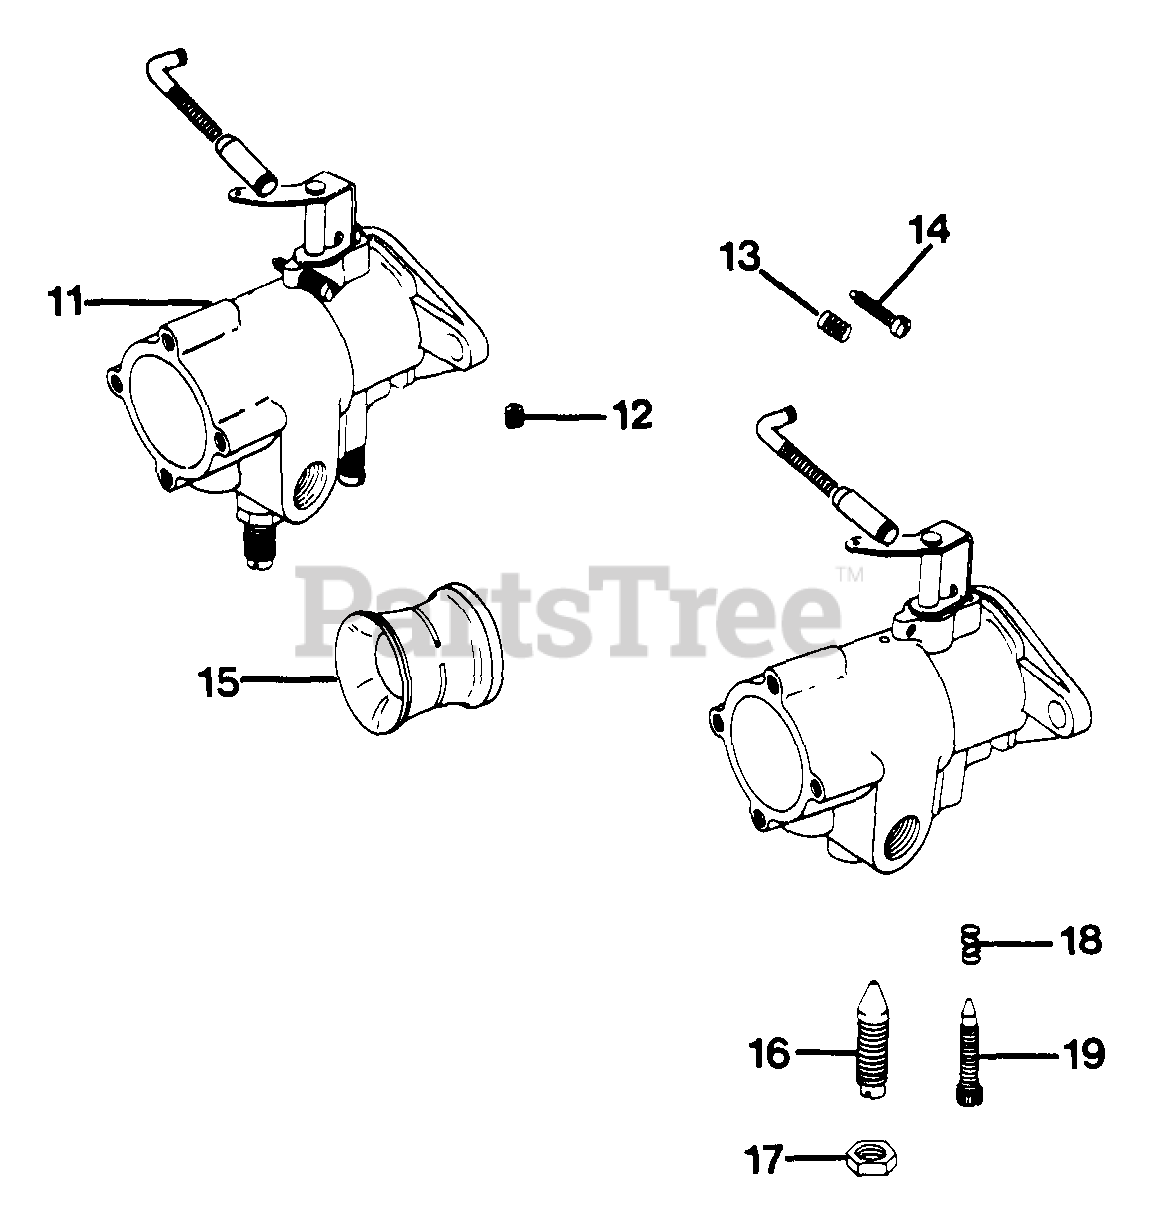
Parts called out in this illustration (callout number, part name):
11	CARBURETOR
14	SCREW, SPECIAL
18	SPRING - DISCONTINUED
19	SCREW - DISCONTINUED
